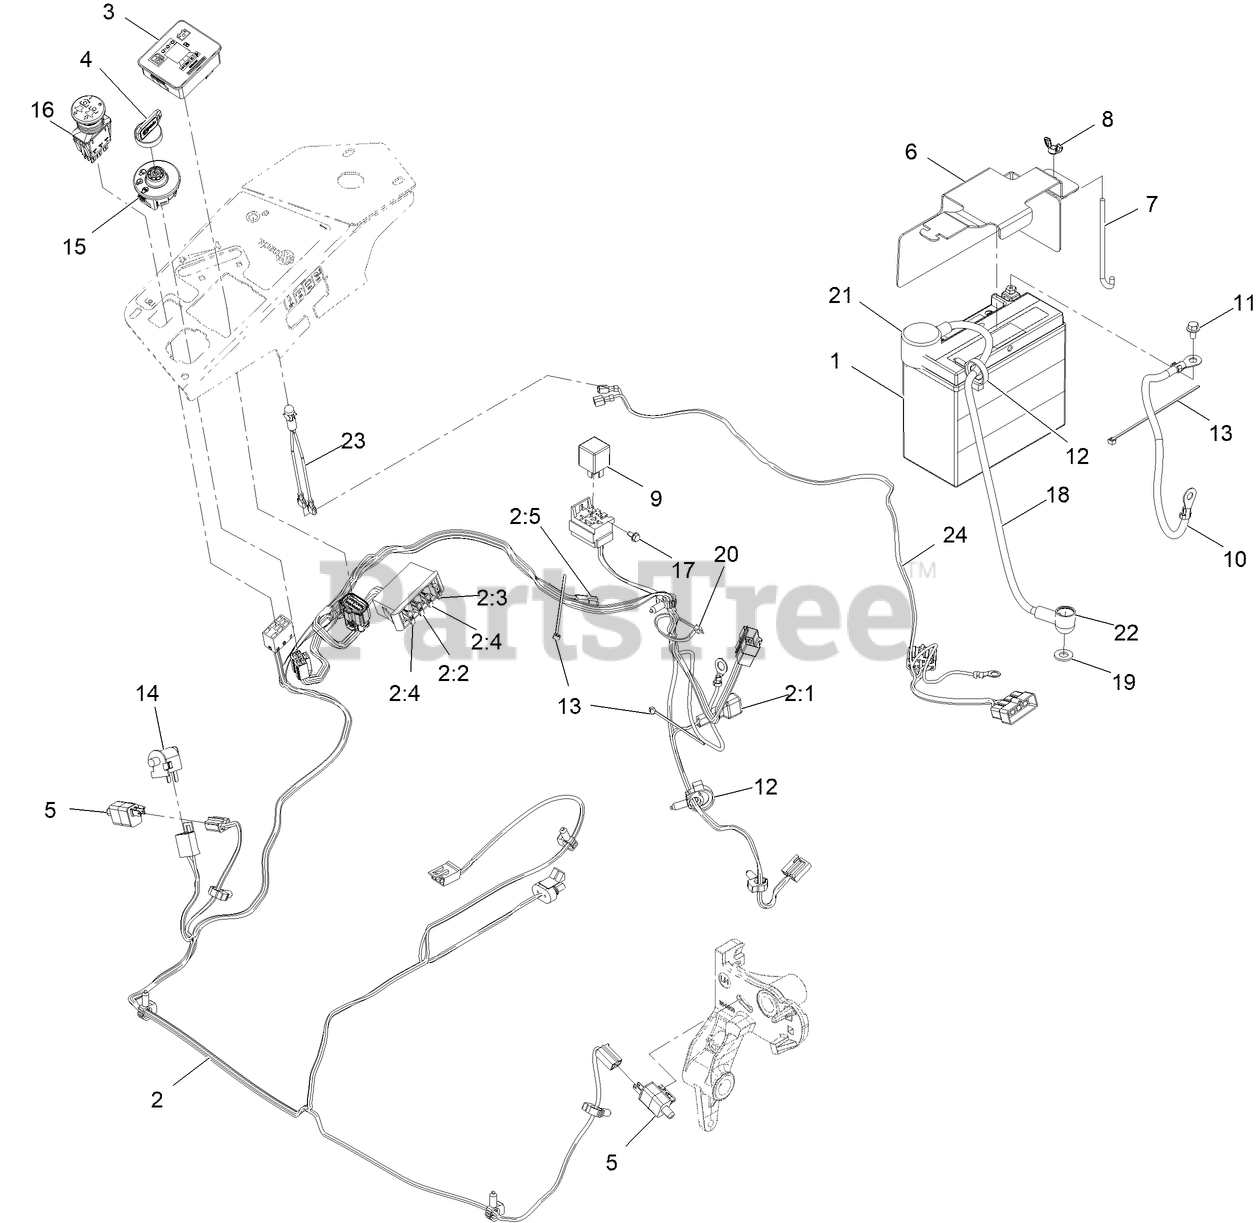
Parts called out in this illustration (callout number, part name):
1	BATTERY-AGM
2	HARNESS-WIRE, MAIN
2:2	FUSE-BLADE, 10 AMP
2:3	FUSE-BLADE, 15 AMP
2:4	FUSE-BLADE, 25 AMP
2:5	CAP-PLUG
3	FUEL/HOUR METER ASM
4	KEYS-IGNITION (SPARE PAIR
4	KEY-IGNITION
6	BRACKET-HOLDDOWN, BATTERY
7	BOLT-HOLDDOWN
8	WINGNUT
10	Cable-Battery, Black
11	SCREW-HHF
12	CLAMP-HOSE
13	TIE-CABLE
14	SWITCH-BAIL
15	SWITCH-IGNITION
16	SWITCH, PTO 10A
17	SCREW-HWH
18	CABLE-BATTERY, POSITIVE
19	WASHER-FLAT
20	TIE-CABLE
21	INSULATOR-BATTERY
22	INSULATOR-SOLENOID
23	INDICATOR-LED, RED
24	HARNESS-INDICATOR LIGHT
